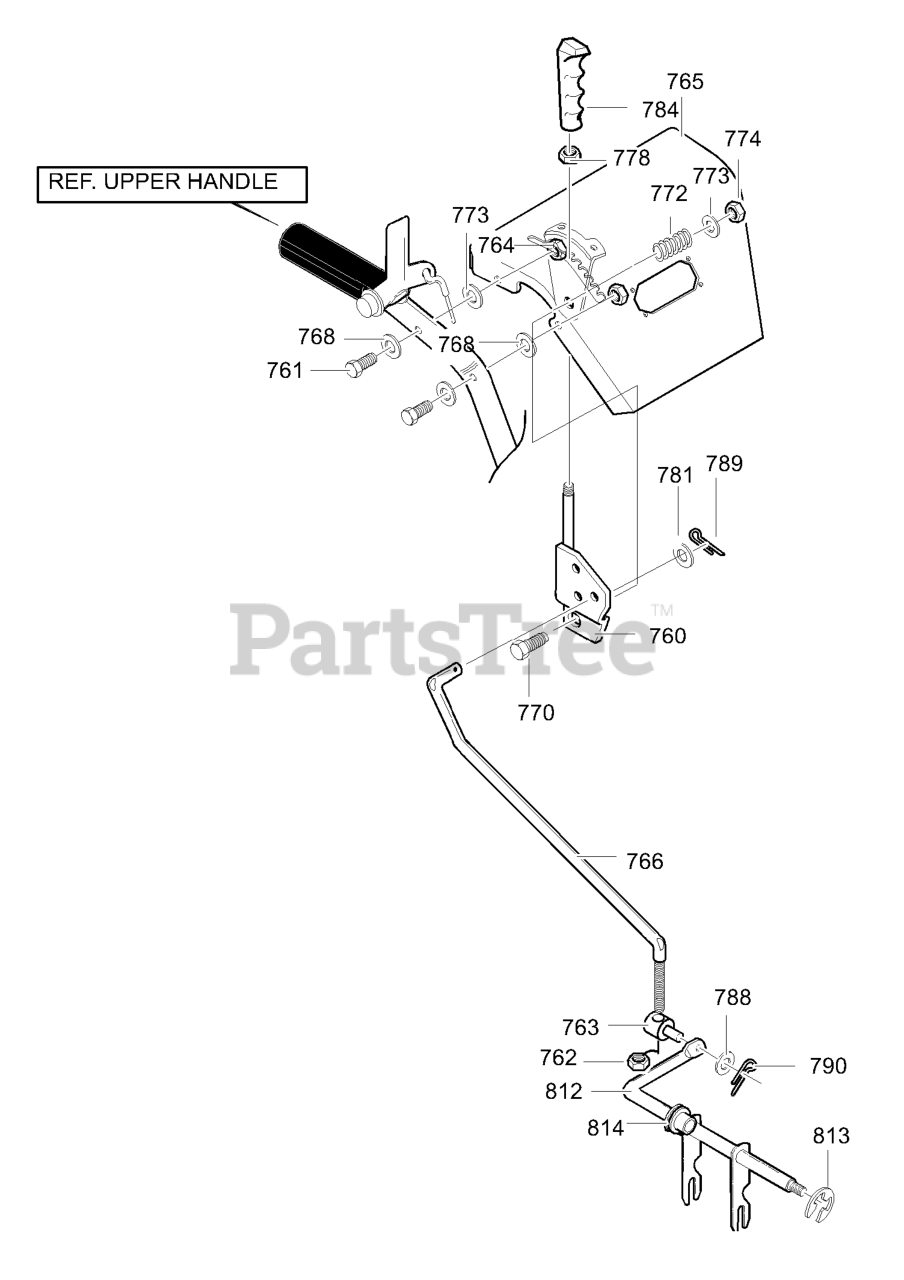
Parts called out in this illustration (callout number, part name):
760	HANDLE ASSY SPD CTRL
761	SCREW, 5/16-18 x 1.75
762	NUT, 5/16-24
763	NUT, TRUNNION
764	NUT, 5/16-18 HEXWDFLLK
765	ASSY. BAY LT
766	ROD, SPEED CONTROL
770	SCREW 3/8-16X2.00
773	FLATWASHER
774	NUT, 3/8-16 HEXNYL
778	NUT, 3/8-16 REGHEX
781	FLATWASHER
784	HANDLE 3/8-16
788	FLATWASHER
789	PIN, COTTER
790	COTTER PIN
812	ROD, ASSY YOKE
813	RING, RETAINER
814	BEARING, FLANGE
